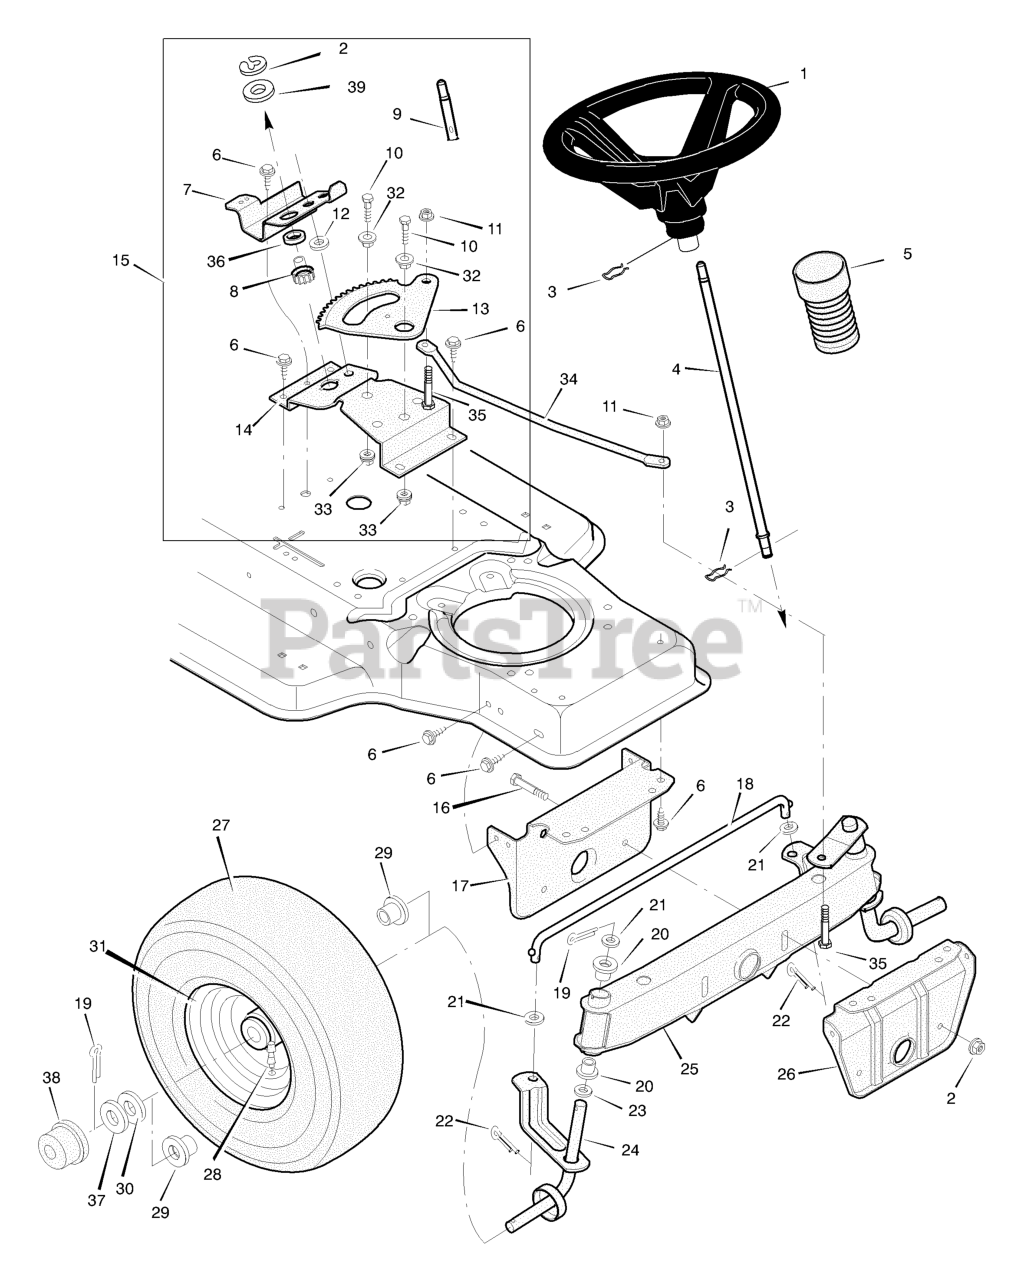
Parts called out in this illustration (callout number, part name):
1	Wheel, Steering
2	E-Ring
3	Retainer, Spring
4	Post, Steering
5	Bellows
7	Bracket, Sector
8	Gear, Pinion
9	Adapter, Steering Shaft
10	CAPSCREW, Hex Head, 5/16-18 x 1
11	Locknut, Flange
13	Gear, Sector
14	Bracket, Sector
15	Kit, Steering Sector & Gear
16	Bolt, Hex
17	Support, Rear Axle
19	Pin, Cotter
20	Bearing
22	Pin, Cotter
24	Spindle Assembly, Right
25	Spindle Assembly, Axle & Left
26	Support, Front Axle
28	Stem, Valve
29	Bearing, Wheel
31	Wheel & Tire Assembly
32	Bearing
33	Locknut, Flange
35	Bolt
36	Bearing, Lower Steering
38	Hub Cap
39	WASHER, 1-1.3 16G FLT
